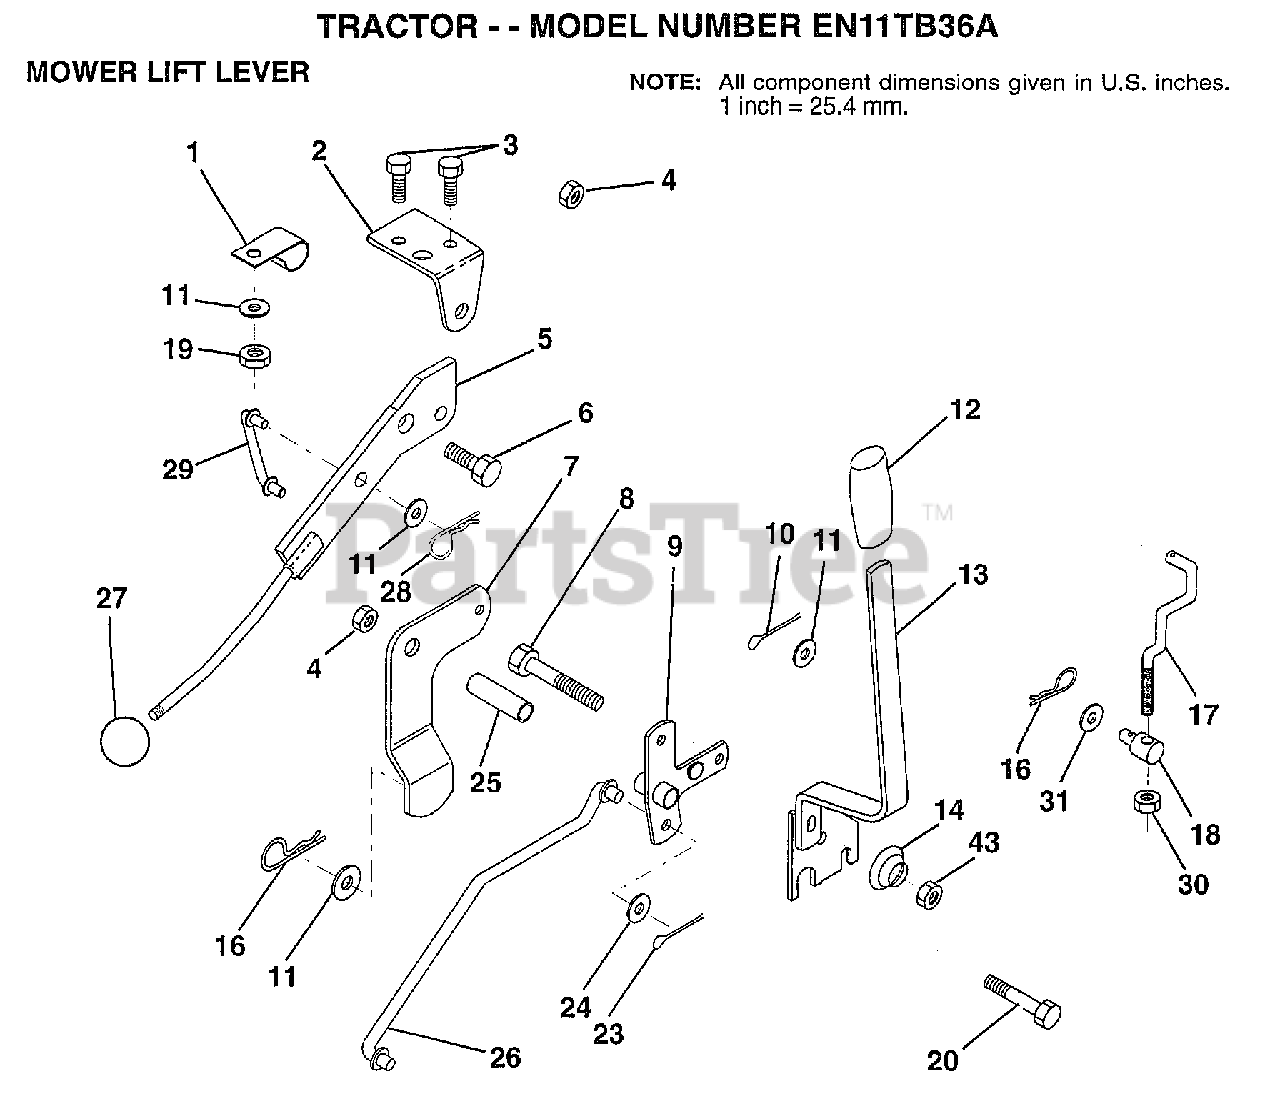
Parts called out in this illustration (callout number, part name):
1	"CLIP,INSULATOR"
2	BRKT CLUTCH
3	BOLT HXHD FIN
5	LEVER.ASM.CLUTCH
6	"BOLT, SHOULDER LT"
7	MWR CLUTCH ARM AS
8	BOLT
9	"BELLCRANK,LIFT"
10	COTTER PIN
11	WASHER
13	HANDLE.ASM.LIFT
14	SPRING COMPRESSIO
16	SPRING.RETAINER
17	"LINK,LIFT FRT"
18	TRUNION ADJ
20	BOLT
23	PIN COTTER 1/8
25	TUBE SPACER
26	ROD LIFT MOWER
27	KNOB T(3/8 HOLE)
28	RETAINER M
29	CLUTCH LINK
30	NUT
31	WASHER
